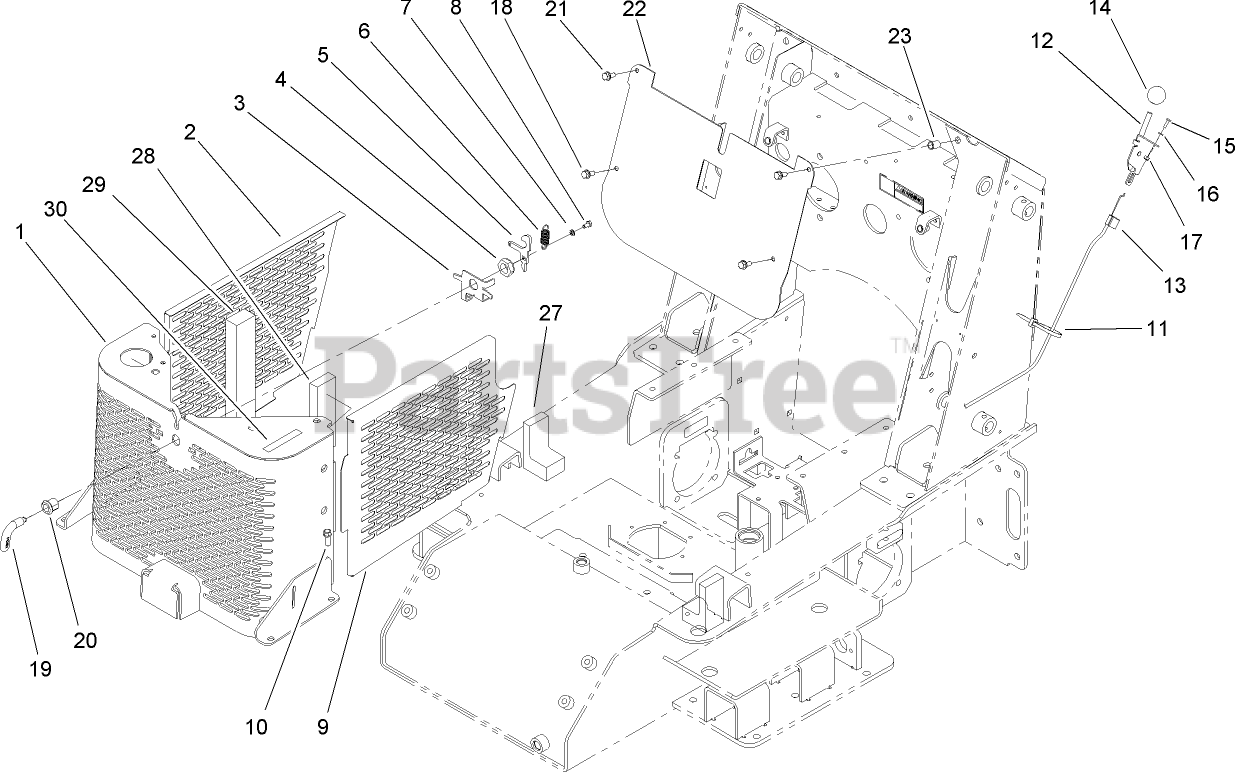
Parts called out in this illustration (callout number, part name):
1	GRILL ASM
2	PANEL-SIDE, RH
3	BRACKET-LATCH
4	NUT-LOCK, NI
5	CAM-LATCH
6	SPRING
7	WASHER-LOCK
8	SCREW-HH
9	PANEL-SIDE, LH
10	SCREW-TAPTITE
11	TIE-CABLE
12	LEVER-CONTROL
13	CABLE-THROTTLE
16	WASHER-FLAT
17	NUT-LOCK, NI
18	SCREW-HHF
19	HANDLE-LATCH
20	HOUSING-LATCH
21	SCREW-HSBH
22	BAFFLE-ELECTRICAL
23	INSERT-THREADED
27	SEAL-FOAM
28	SEAL-FOAM
29	SEAL-FOAM
30	DECAL-WARNING, FAN
